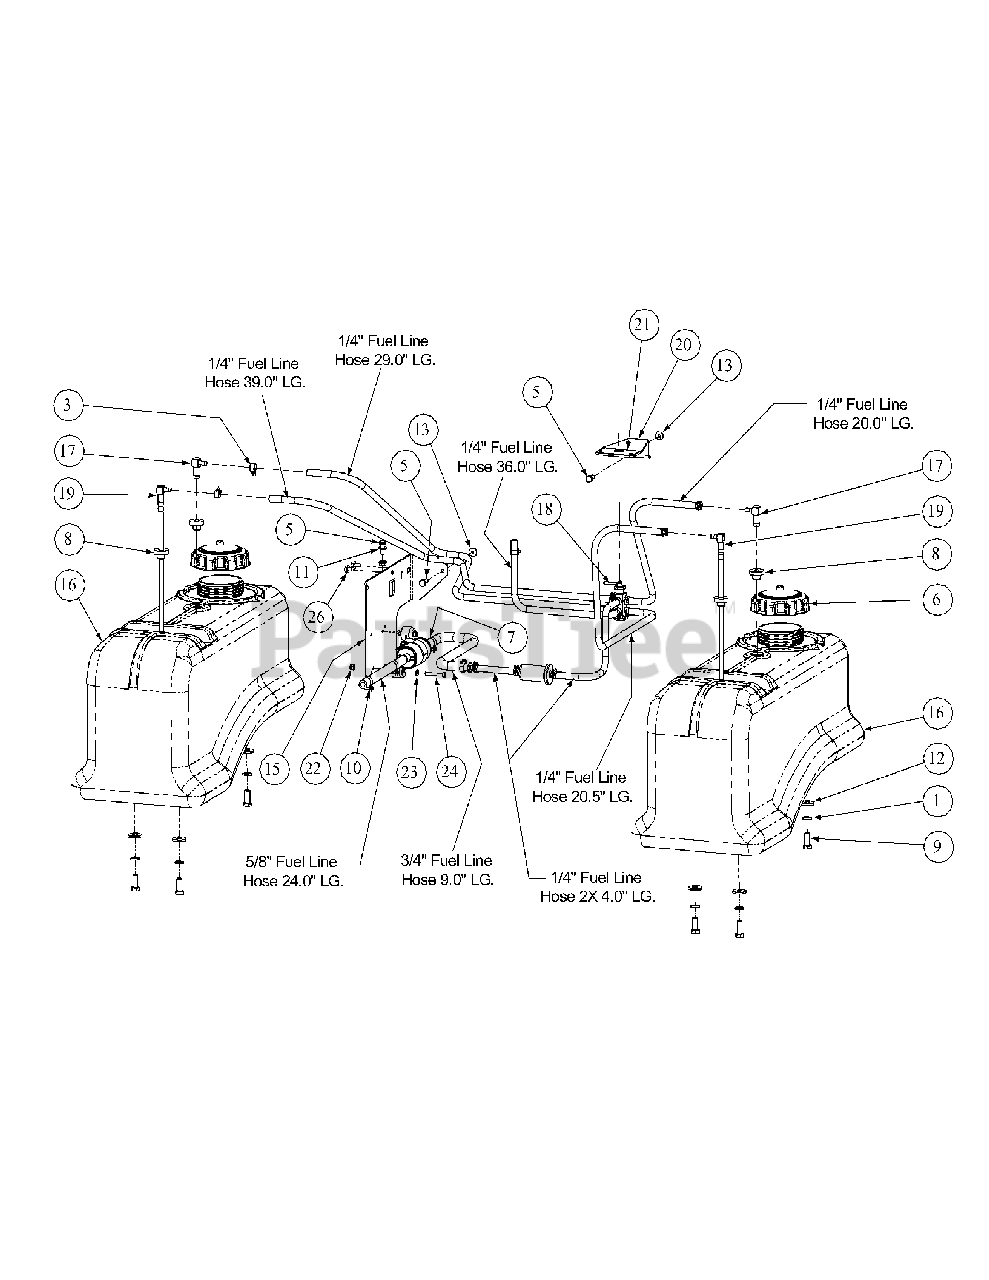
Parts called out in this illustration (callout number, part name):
1	Lock Washer, 3/8
2	Hose, 1/4" Fuel Line, 152.5"
3	Clamp, Union
4	Cable Tie
5	Hex Cap Screw, 1/4-20 x 3/4
6	Fuel Cap, 3.5
7	Hose Clamp
8	Fuel Tank Grommet
9	Hex, Cap Screw, 3/8-16, .88
10	Hose Clamp, High Pressure
11	Washer, 5/16
12	Flat Washer, .406 ID, 1.0 OD, .105
13	Hex Flange Lock Nut, 1/4-20
14	Fuel Hose, .38 ID x .625 OD, 24"
15	Pump Mounting Bracket
16	Fuel Tank
17	Fuel Fitting, Return
18	Shut Off Fuel Valve
19	Fuel Fitting, Pickup
20	Fuel Valve Mounting Bracket
21	Decal, Fuel Tank Shut Off
22	Nut, 10-24, Nylon Insert
23	Washer, 3/16
24	Socket Head Screw, 10-24 x 1.25
25	Fuel Hose, .50 ID x .75 OD, 9"
26	Self Tapping Screw, 1/4-20 x .50
